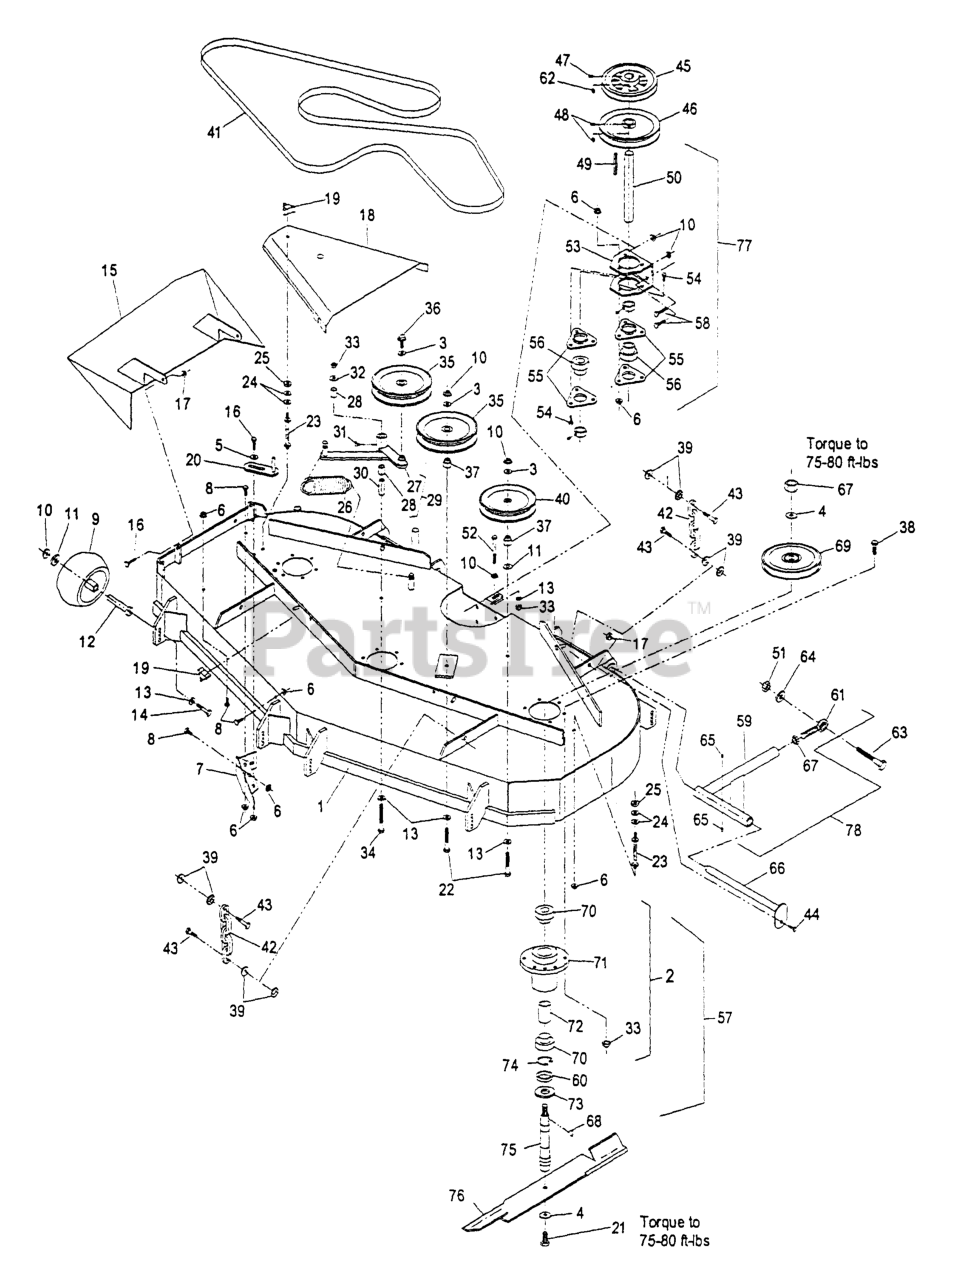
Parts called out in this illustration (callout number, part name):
4	WASHER-SPRING
5	WASHER-SPRING
7	WLD,BAFFLE DISCHARGE
9	ROLLER-SCALP, ANTI
12	BUSHING-ROLLER
18	SHIELD,BELT
19	KNOB-3 PRONG
20	GUIDE-BELT
23	STUD-SHIELD, BELT (SHORT)
28	SLEEVE-BEARING
30	BUSHING
37	BUSHING-IDLER
40	PULLEY-IDLER
41	BELT,BLADE DRIVE
42	CHAIN-LIFT, DECK
43	SCREW-CAP, HH
45	SHEAVE,BLADE DRIVE
46	SHEAVE,SPLIT STEEL
48	SCREW-SET
49	KEY,MACH 1/4X1/4X2-5/8
50	JACKSHAFT,DECK DRIVE
53	BRACKET,JACKSHAFT
55	HOUSING-FLANGE
56	BEARING,W/COLLAR
57	SPINDLE HSG.ASSY.COMP.
60	SPACER-PULLEY/BEARING
61	BALLJOINT-SPHERICAL
62	SCREW-SET
66	PIN-STRUT
69	SHEAVE,BLADE DRIVE
70	BEARING
72	SPACER-BEARING
73	GUARD-BEARING, BOTTOM
75	SHAFT,SPINDLE 604
77	DK DR. BRG. ASSY
